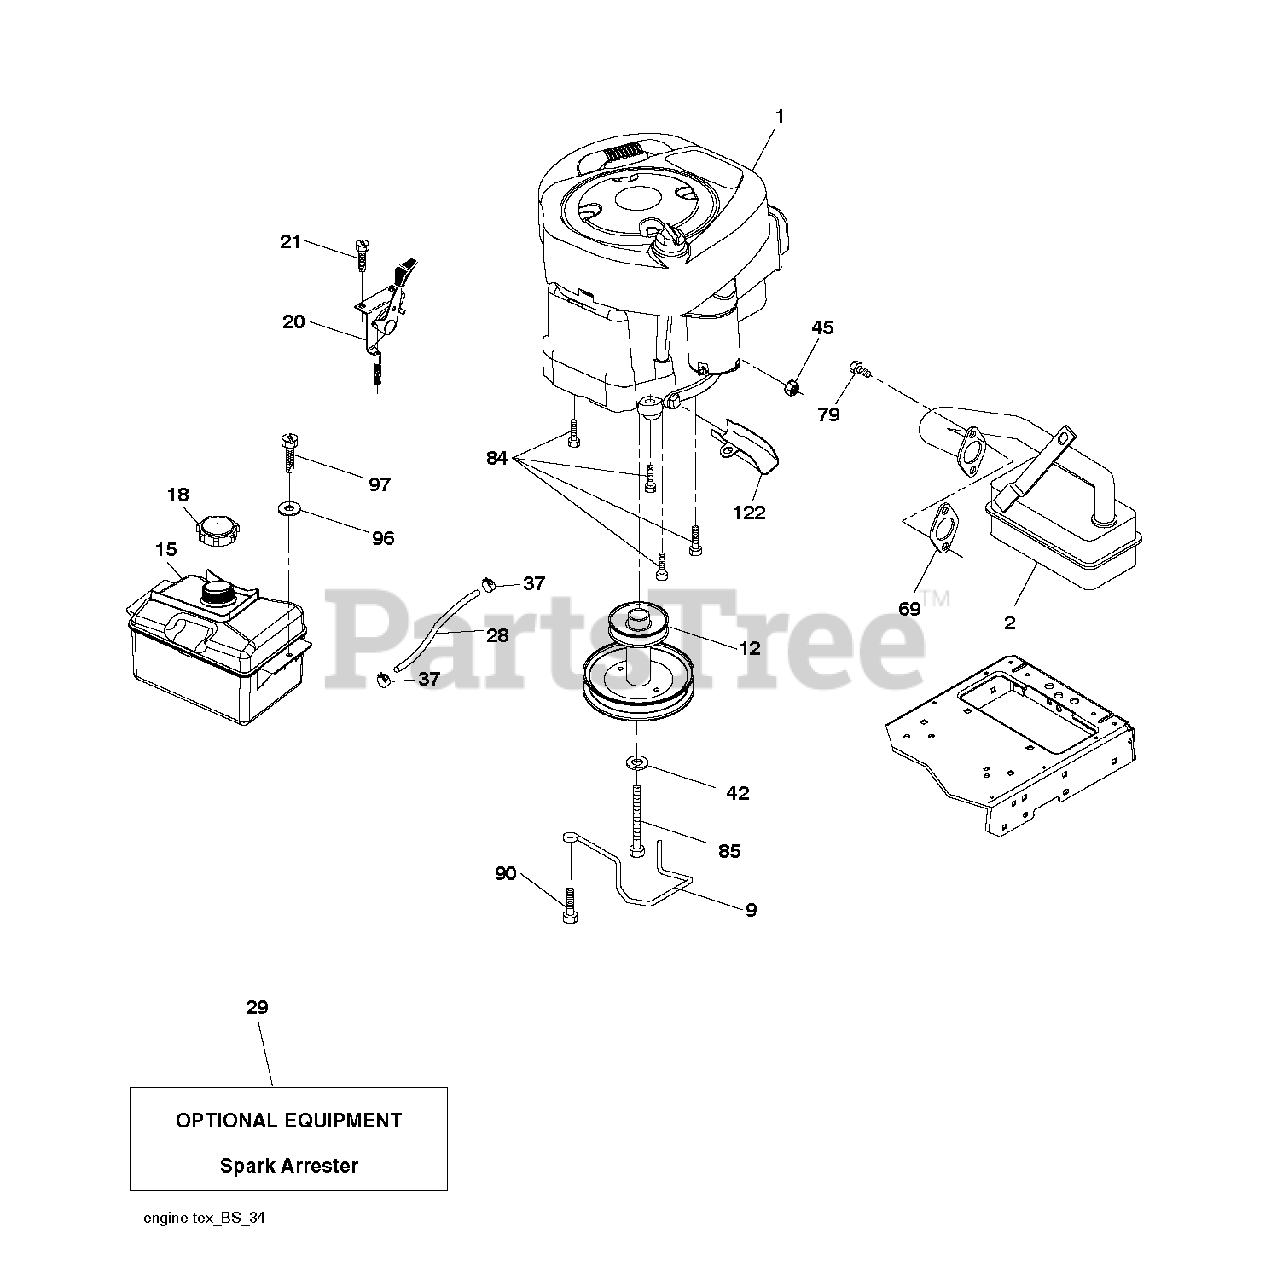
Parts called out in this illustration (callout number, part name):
9	KEEPER.BELT.ENGINE.3.25
12	PULLEY ENGINE
15	TANK FUEL FRT 1.5 GAL
18	CAP ASM.FUEL.2.25"FR.
20	CONTROL.THCK.COBRA.BS
21	SCREW.#10 X 0.750.BOS THREAD
29	ARRESTER SPARK (OPTIONAL)
42	LOCKWASHER
45	NUT
69	REPL BY 532 27 22-93
79	SCREW.SOCKET HD.5/16-1
85	BOLT HEX 7/16-20X4-1/4"
90	SCREW 3/8-16X1
97	SCREW HEXWSHR 1/4-20X3/4
122	EXTENSION DRAIN OIL
